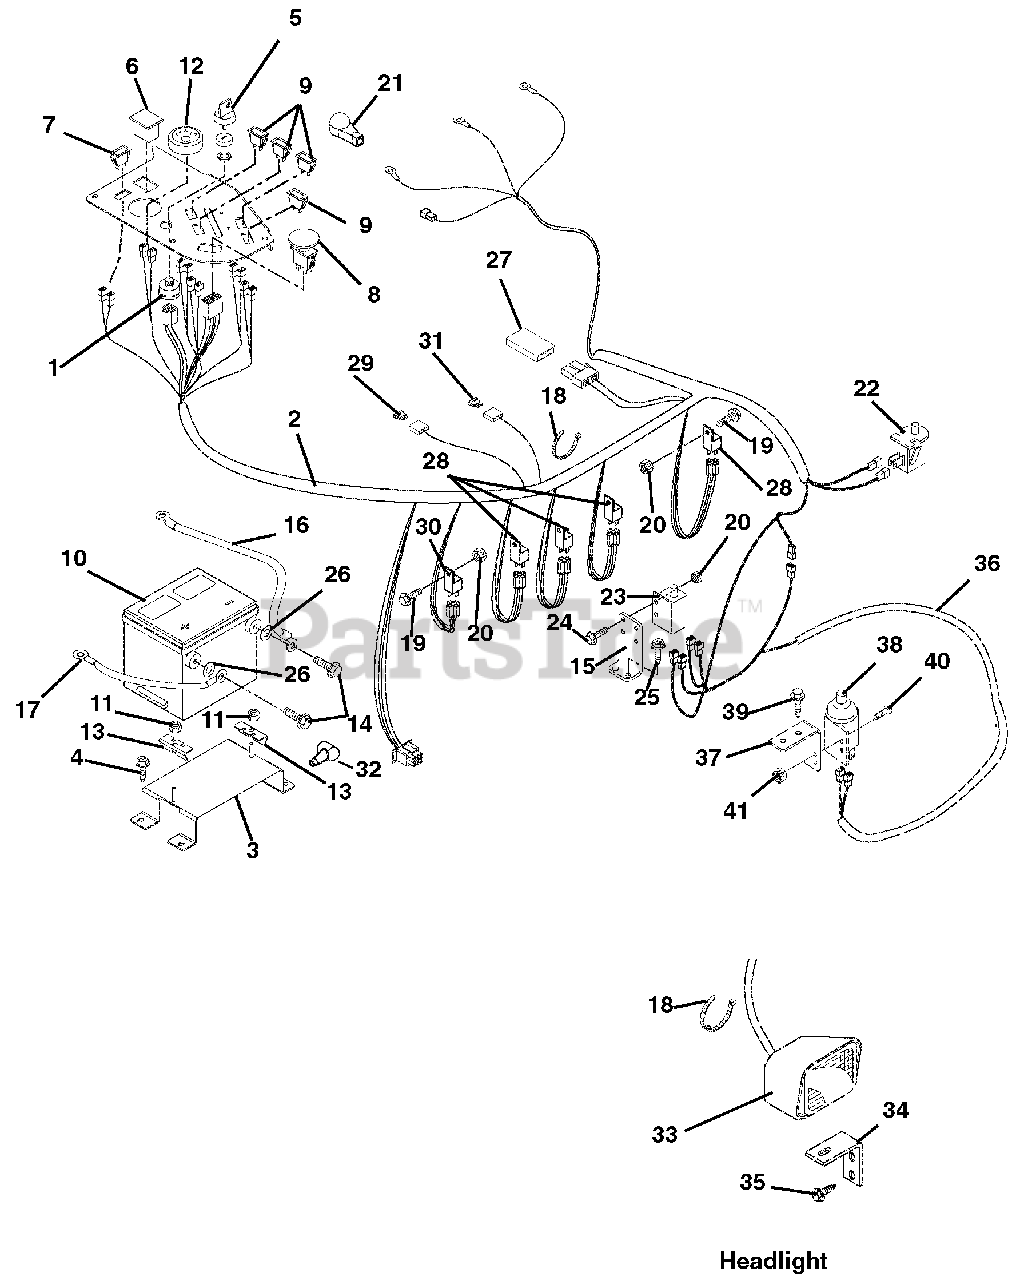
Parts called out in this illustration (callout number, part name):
1	SWITCH, IGNITION
2	HARNESS-MZ HORIZ L/C DIESEL
3	WMT, BATTERY SUPPORT
4	@SCR-TAP .38-16X.75 HWH TR YWZ
5	KEY, W/ SHIELD
5	IGNITION KEY SET
6	METER, HOUR W/MAINTENANCE
7	SWITCH, 2 POLE/ROCKER
8	SWITCH, CLUTCH
9	LIGHT,INDICATOR
10	BATTERY, GROUP 70 450 CCA 35 A
11	@NUT-LK-TOP-FLG .31-18 YWZC
12	GAUGE, TEMPERATURE
13	BRKT, BATTERY HOLD-DOWN
14	BATT TERMINAL SCREW
15	MOUNT, SAFETY SWITCH
16	CABLE - POS BATT W/BOOTS 4X48
17	CABLE, NEGATIVE BATTERY 49.00
18	CABLE TIE LG 5-1/2
19	@SCR-MCH 10-24X.75 HWH YWZC
20	@NUT-LK-NYL 10-24 W/INSRT YWZC
21	BOOT, TERMINAL, RED
22	SWITCH- SNAP MTG N.O.
23	SWITCH- DOUBLE POLE N.O./N.O.
24	@SCR-MCH 10-24X.75 HWH YWZC
25	@SCR-TAP .25-20X.50 HWH TR YWZ
26	@WSHR-FL-STL.38X.875X.083 YWZC
27	DIODE, CONNECTOR SHELL
28	RELAY,SEALED W/DIODE
29	FUSE, ATO 30 AMP
30	Pre-Heat Timer
31	FUSE, ATO 60 AMP
32	BOOT, BATTERY TERMINAL-RED
33	HEADLIGHT
34	BRACKET, HEADLIGHT MTG
35	@SCR-TAP .38-16X.50 HWH TR YWZ
36	HARNESS, WIRE ADAPTER CE
37	MOUNT - SWITCH
38	SWITCH-SINGLE POLE N.O.W/COVER
39	@SCR-TAP .31-18X.50 HWH TR YWZ
40	@SCR-MCH 10-24X.75 HWH YWZC
41	@NUT-LK-NYL 10-24 W/INSRT YWZC
